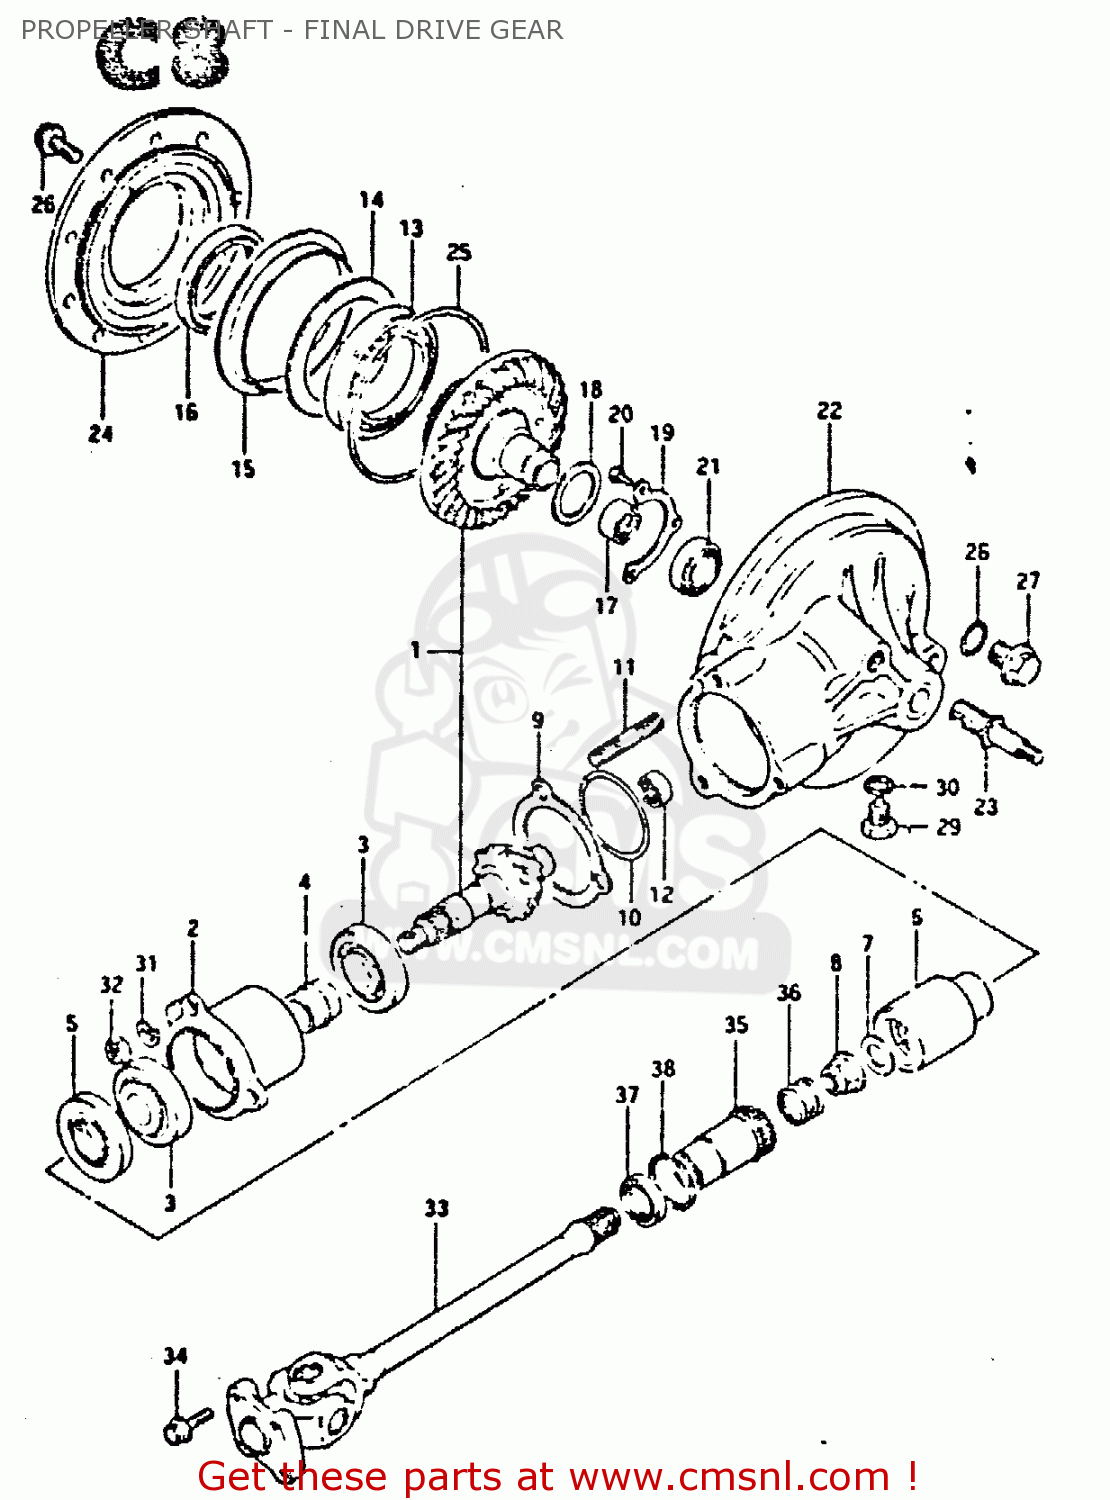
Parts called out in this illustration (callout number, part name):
1	GEAR SET,FINAL BEVEL (N
2	HOUSING,DRIVE GEAR
3	BEARING
4	SPACER
5	SEAL,OIL(32X54X7)
6	GEAR,FINAL DRIVE
7	WASHER(14X29X4)
8	NUT
9	SHIM,DRIVE GEAR HOUSING
10	O RING(D:2.4,ID:62.6)
11	STUD 10X30
12	BEARING
13	BEARING(70X110X13)
14	SHIM,DRIVEN GEAR BEARING T0.35
15	PLATE,FINAL DRIVEN BRG OIL
16	SEAL,OIL(70X96X16)
17	BEARING(32X46X17.7)
18	SHIM,FINAL DRIVEN GEAR
19	RETAINER,FINAL DRIVEN GEAR BRG
20	SCREW 6X12
21	SEAL,OIL(30X42X7)
22	CASE,FINAL GEAR
23	STUD
24	CASE,FINAL GEAR BEARING
25	O RING(D:3.5,ID:131.6)
26	BOLT
27	PLUG
28	O RING(D:2.4,ID:17.8)
29	PLUG
30	GASKET(14X19.2X2) (NAS)
31	LOCK WASHER
32	NUT
33	SHAFT ASSEMBLY,PROPELLER
34	BOLT(8X17)
35	COUPLING,PROPELLER SHAFT
36	SPRING
37	SEAL,OIL(30X40.5X5.5)
38	CIRCLIP
